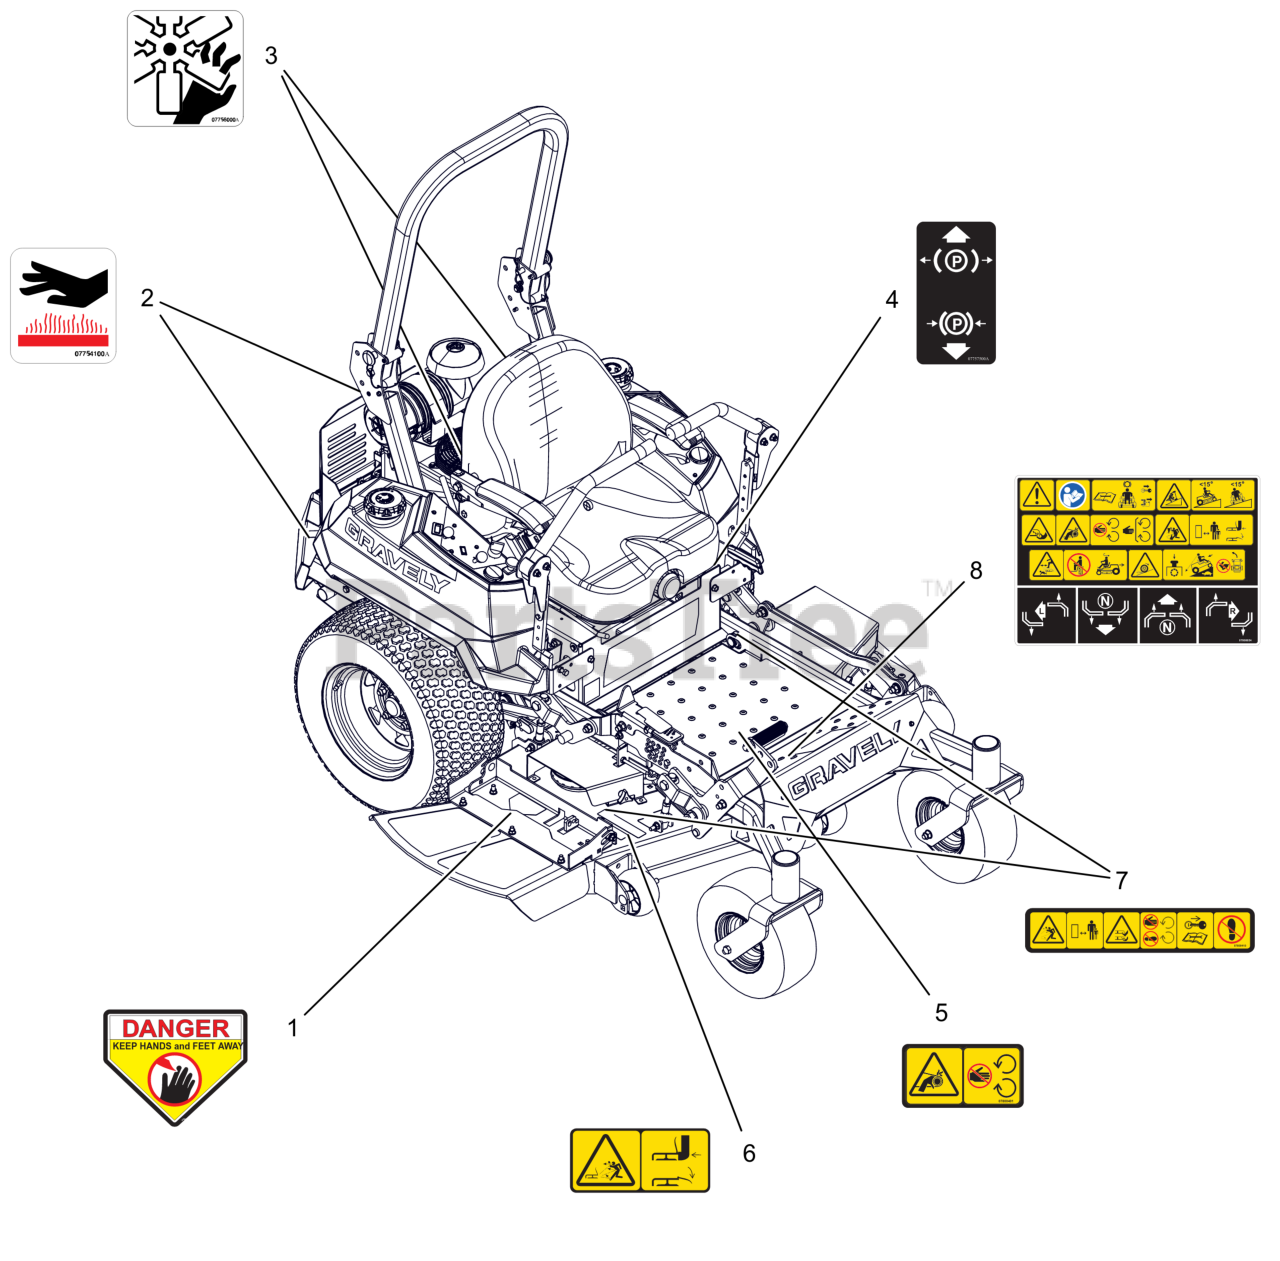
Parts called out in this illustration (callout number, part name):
1	DECAL, DANGER
2	DECAL, HOT SURFACE
3	DECAL, DANGER FAN
4	DECAL, PARKING BRAKE LEVER
5	DECAL, SAFETY - GUARDING
6	DECAL, SAFETY - DECK GUARDING
7	DECAL, DECK SAFETY
8	DECAL, INSTR SAFETY
